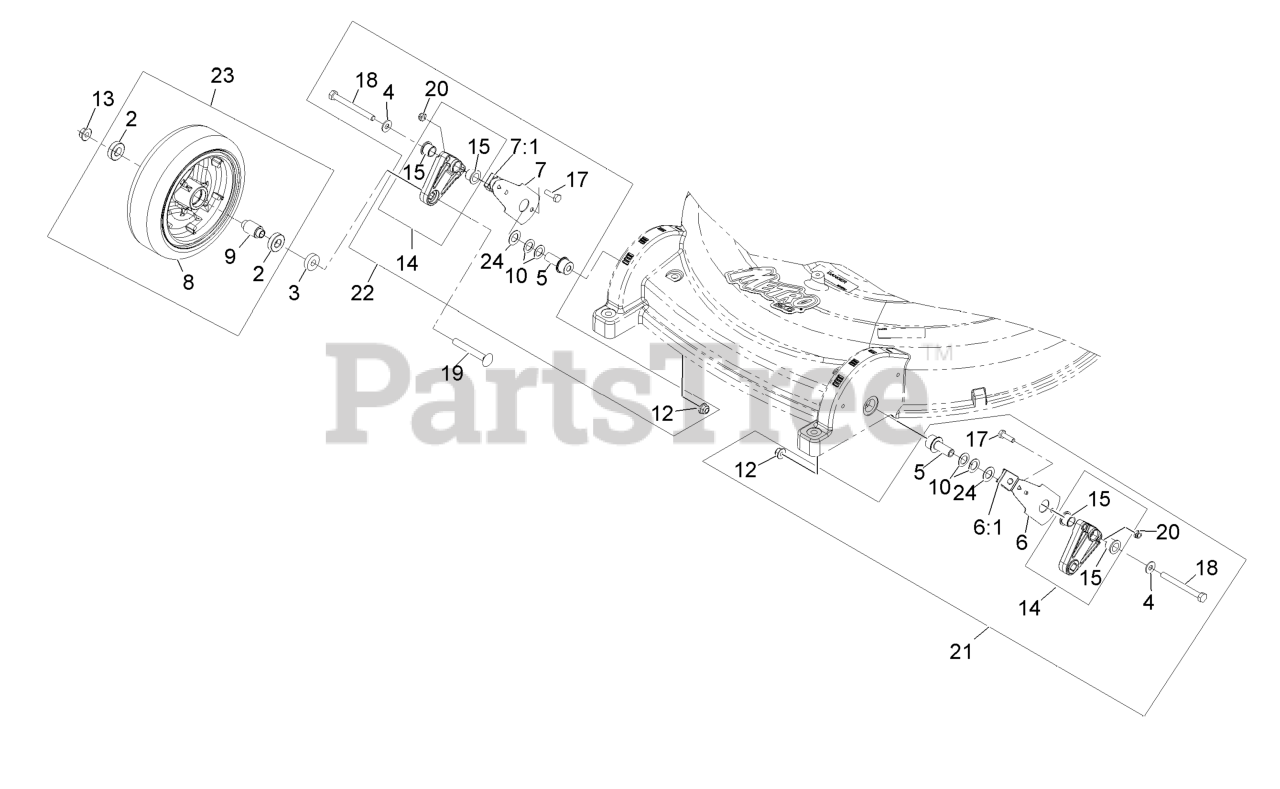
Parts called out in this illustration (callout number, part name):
2	BEARING-WHEEL
4	WASHER-FLAT
5	BUSHING-PIVOT, WHEEL
6	KIT,SPRING ARM FRONT LH
6:1	KNOB-ARM
7	KIT,SPRING ARM FRONT RH
7:1	KNOB-ARM
8	ASM,8" WHEEL AND TIRE
9	SPACER-WHEEL, FRONT
10	WASHER-CONICAL
12	NUT-HF, NI
13	NUT-HF, NI
14	ASM-FRONT WHEEL ARM
15	BEARING-FLANGE
17	SCREW-HH
18	SCREW-HH
19	SCREW-CARR
20	NUT-LOCK, NI
21	ASM-LH PIVOT
22	ASM-RH PIVOT
23	8 INCH WHEEL ASM
24	WASHER-PLAIN
